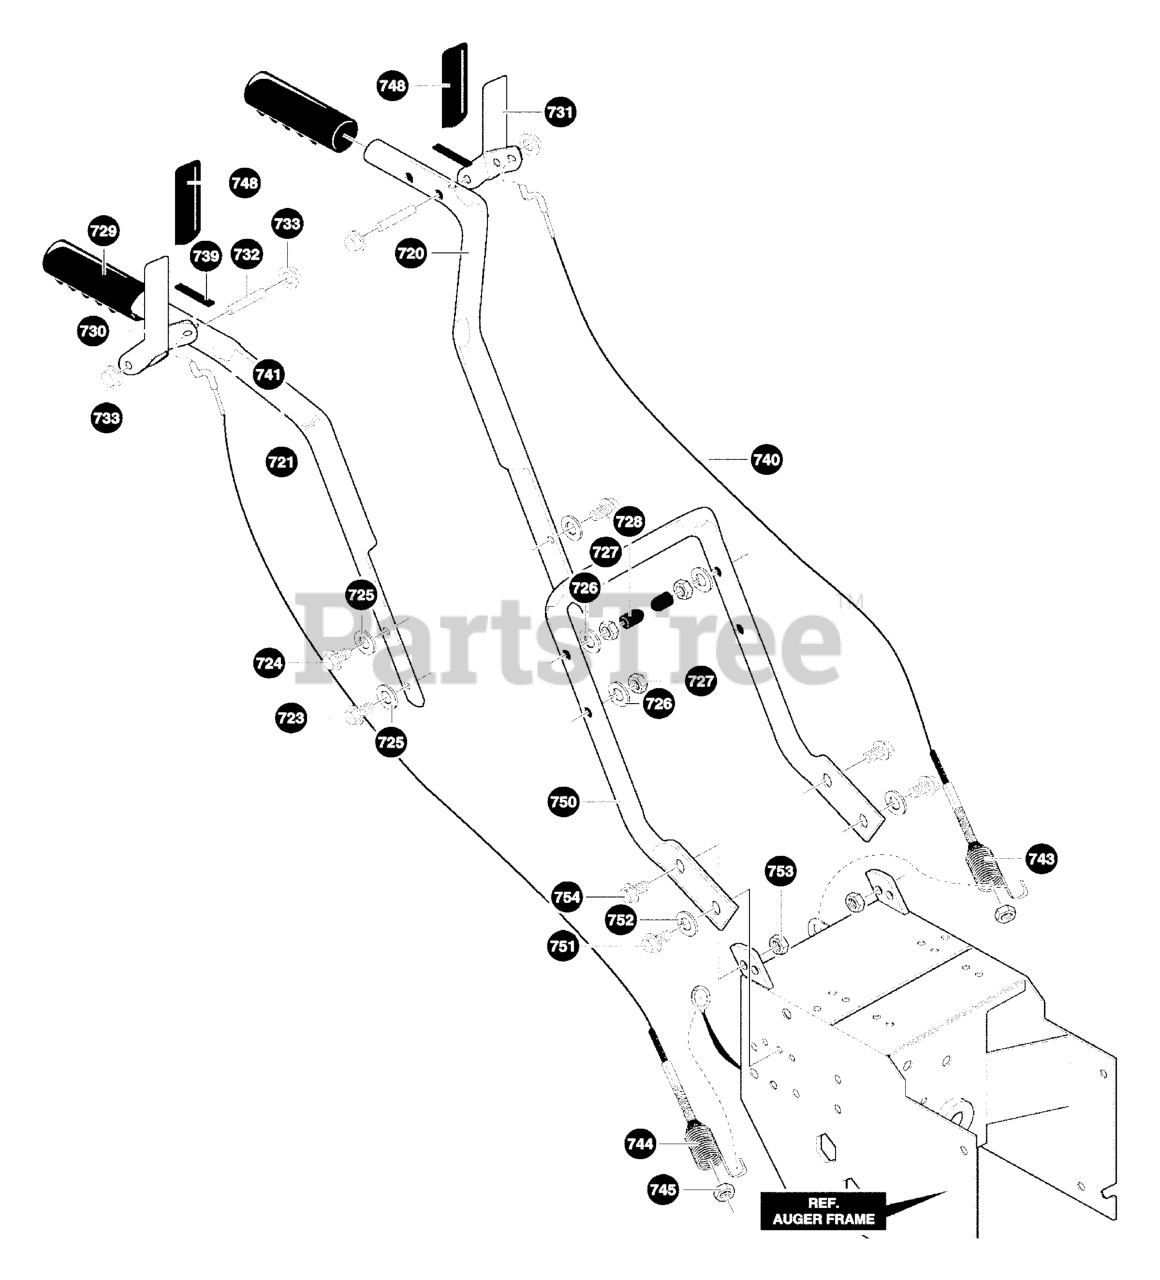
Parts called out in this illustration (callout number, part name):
720	HANDLE, UPPER LH
721	HANDLE, UPPER RH
723	SCREW, 3/8-16 x 2.00
724	SCREW, 3/8-16 x 3.00
725	WASHER, FLAT
726	WASHER, .38ID
727	NUT, 3/8-16 REGHXCTRLK
728	STOP, PLASTIC
729	GRIP, HANDLE
730	ASSY, CLUTCH LEVER RH
731	ASSY, CLUTCH LEVER LH
732	PIN, PIVOT CLUTCH
733	NUT, PUSH ON CAP
739	BUMPER, REC
740	CABLE, CLUTCH 32.19
741	CABLE, CLUTCH 28.50
743	SPRING, TENSION
744	SPRING, AUGER CLUTCH
745	NUT, 1/4-20 HEX NYLOCK
748	GRIP, CLUTCH HANDLE
750	HANDLE, LOWER
751	SCREW, 5/16-18 x 0.75
752	WASHER, .31X.58X.08
760	ASSY, PANEL
761	SCREW 5/16-18X1.75
762	FLATWASHER
764	NUT 5/16-18 HEXWDFLLK
766	PLATE, PANEL
